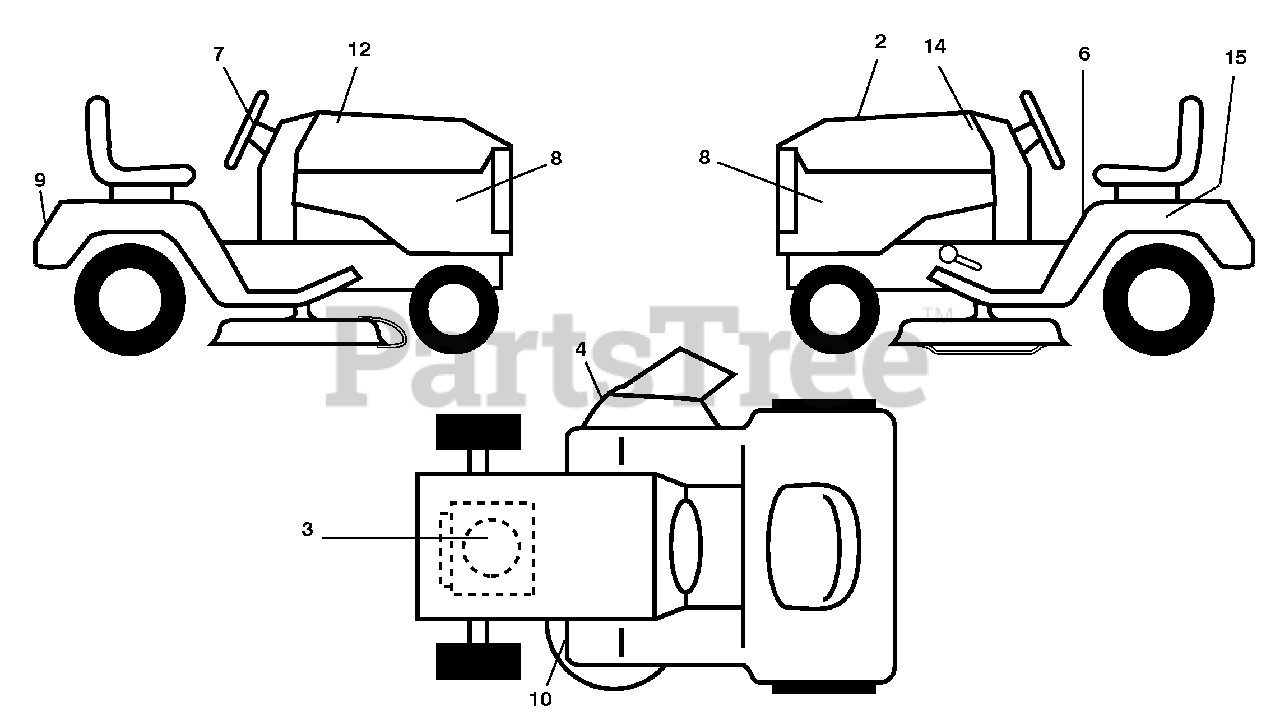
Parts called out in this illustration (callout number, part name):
2	Decal, Replacement
3	Decal, Engine HP
4	Decal, Warning
6	Decal, Fender Danger English/French
7	Decal, Ins Str Wh
8	Decal, Side Panel
9	Decal, Fender
10	Decal, V-Belt Sch.
12	Decal, Hood RH
14	Decal, Hood LH
15	Decal, Caution, Battery
15	Decal, Handle Lft Height Adj.
15	Manual, Operator's (E&F)
15	Manual, Parts (E&F)
